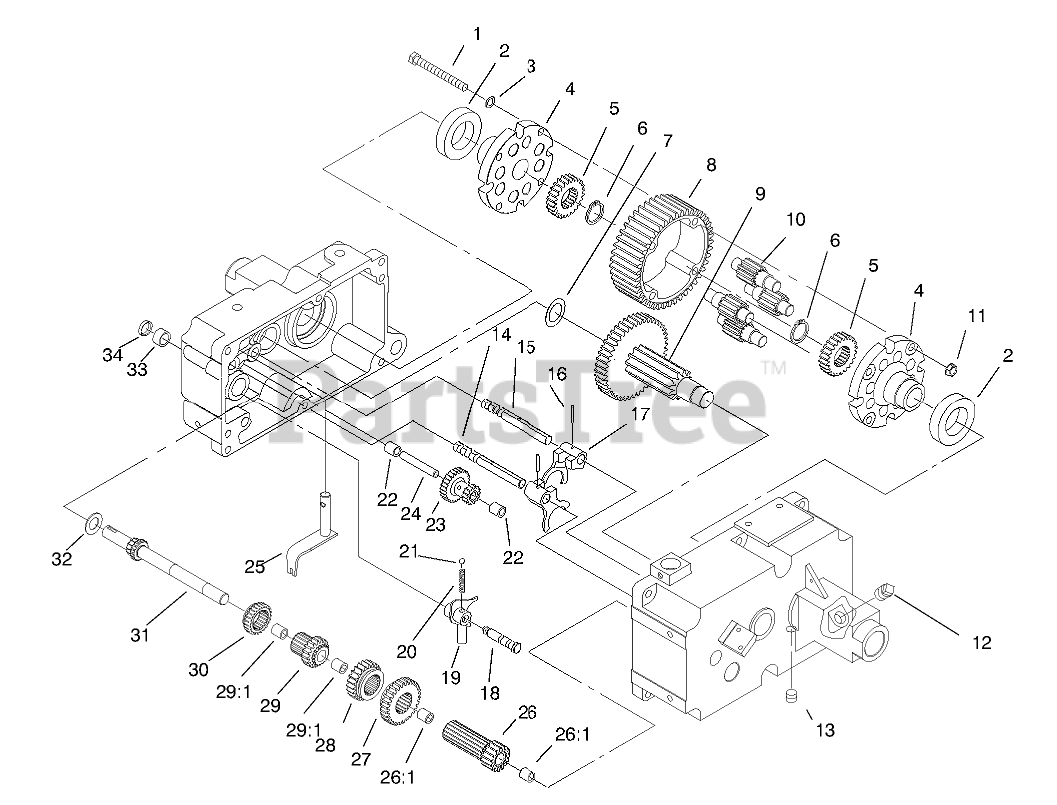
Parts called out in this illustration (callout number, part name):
1	BOLT-HEX
2	BEARING-BALL
3	WASHER
4	END CAP-DIFFERENTIAL
5	GEAR-AXLE DIFFERENTIAL
6	RING-SNAP
7	WASHER-THRUST
8	GEAR-DIFFERENTIAL RING, 43T
9	GEAR ASM
10	GEAR-PINION, 11T
12	PLUG-PIPE, SQH
14	RAIL-SHIFT
15	RAIL-REAR SHIFT
16	PIN-ROLL
17	FORK-SHIFT
18	BOLT-DETENT
19	SHIFT FORK ASM
20	SPRING-SHIFT STOP
21	BALL-DETENT
22	BEARING-NEEDLE
23	Gear
24	GEAR-SHAFT REDUCTION
25	SHIFT ASM
25:1	Shift Lever
25:2	Shaft-Lever
26	GEAR
26:1	BEARING-NEEDLE
27	GEAR-LOW AND REVERSE
28	GEAR-HI AND 2ND
29	Gear
29	GEAR
29:1	BEARING-NEEDLE
30	GEAR-SLIDING
31	SHAFT-INPUT
32	WASHER-THR
33	BEARING-NEEDLE
34	SEAL-OIL
